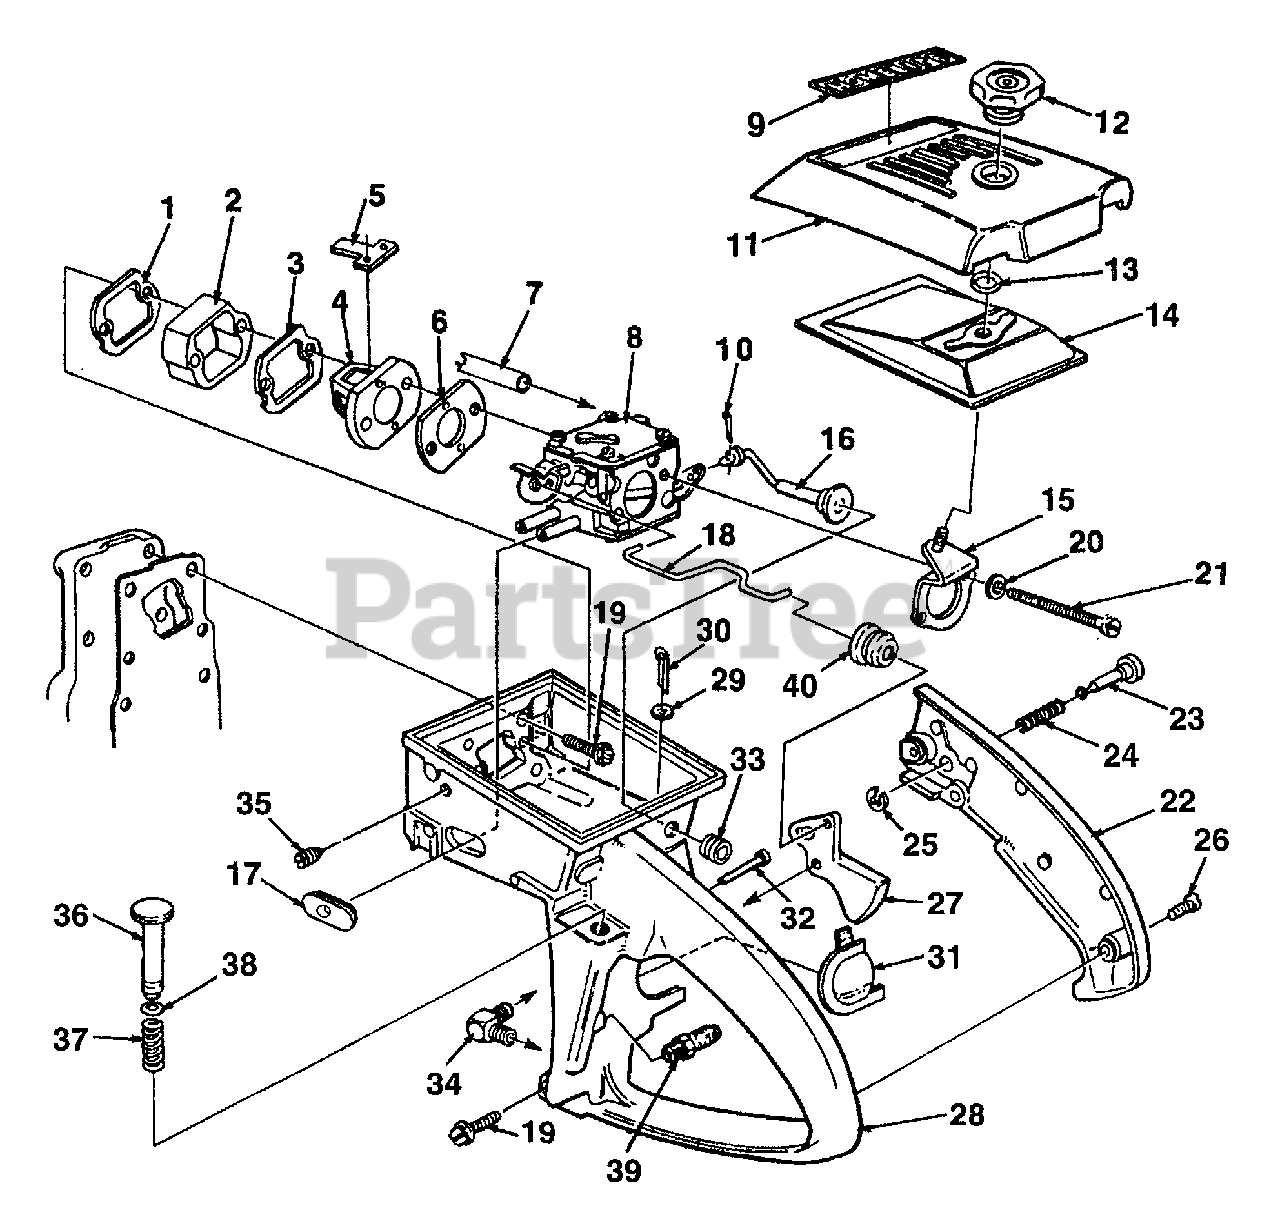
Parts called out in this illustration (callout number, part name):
1	GASKET-Spacer
2	SPACER-Heat Dam
3	RETAINER-Reed Valve
4	SEAT-Reed Valve
5	VALVE-Reed
6	GASKET-Carburetor
7	LINE-Fuel (9 1/4")
8	CARBURETOR-Walbro
9	LABEL-Homelite
10	PIN-Cotter
11	COVER-Air Filter
12	NUT-Air Filter Cover
13	RING-Retaining
14	ELEMENT-Air Filter
15	BRACKET-Mounting
16	ROD-Choke
17	GROMMET KIT
18	ROD-Throttle
19	SCREW-Hex (12-24 X 7/8")
20	WASHER-Lock (#10)
21	SCREW-Hex (10-32 X 2 11/16")
23	PIN-Throttle Latch
24	SPRING-Throttle Latch
25	RING-Retaining
26	SCREW-Pan (8-32 X 1/2")
27	TRIGGER-Throttle
29	WASHER-Felt
30	PIN-Cotter
31	SHIELD-Spark Plug
32	PIN, Oil Plunger Retaining
33	VALVE-Check
34	SCREW-Idle
35	GROMMET KIT
36	PLUNGER-Spring
37	SPRING-Compression
38	"O" RING
39	VALVE-Check
40	BOOT- Throttle Rod
